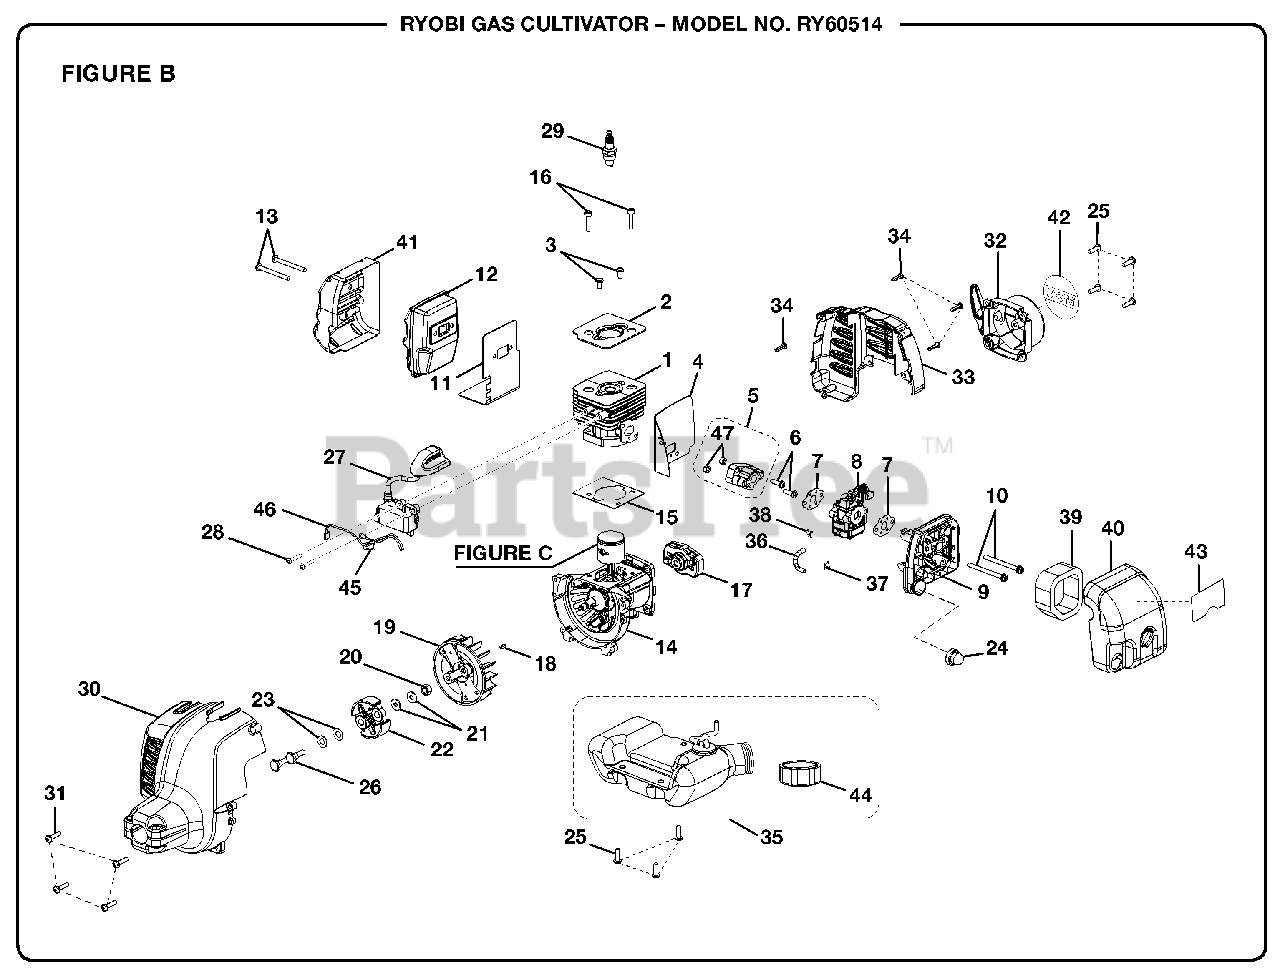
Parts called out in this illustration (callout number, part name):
1	Cylinder
2	Cylinder Plate
3	Screw w/Washer (M5 x 10 mm Pan Hd.)
4	Insulator Gasket
5	Insulator
6	Screw (M5 x 31 mm Torx Pan Hd.)
7	Carburetor Gasket
8	Carburetor Assembly
9	Air Filter Base
10	Screw (M5 x 60 mm Pan Hd.)
11	Muffler Gasket
12	Muffler Assembly
13	Screw (M5 x 50 mm Pan Hd.)
14	Crankcase Assembly
15	Cylinder Gasket
16	Screw (M5 x 22 mm Torx Pan Hd.)
17	Pulley Assembly
18	Woodruff Key
19	Flywheel
20	Hex Nut
21	Washer
22	Clutch Assembly
23	Wavy Washer
24	Primer Assembly
25	Screw (M5 x 16 mm Pan Hd.)
26	Screw (M6 x 14 mm Pan Hd.)
27	Ignition Assembly
28	Screw (M4 x 22 mm Pan Hd.)
29	Spark Plug
30	Front Housing Assembly
31	Screw (M5 x 20 mm Pan Hd.)
32	Starter Housing Assembly
33	Rear Engine Housing
34	Screw (M4 x 16 mm Pan Hd.)
35	Fuel Tank & Cap Assembly
36	Tube
37	Hose Clip
38	Clip
39	Air Filter
40	Air Filter Cover Assembly
41	Heat Shield
42	Logo Label
43	Primer Label
44	Fuel Cap Assembly
45	Lead Wire Assembly, Black
46	Lead Wire Assembly, Red
47	Hex Nut (M5)
